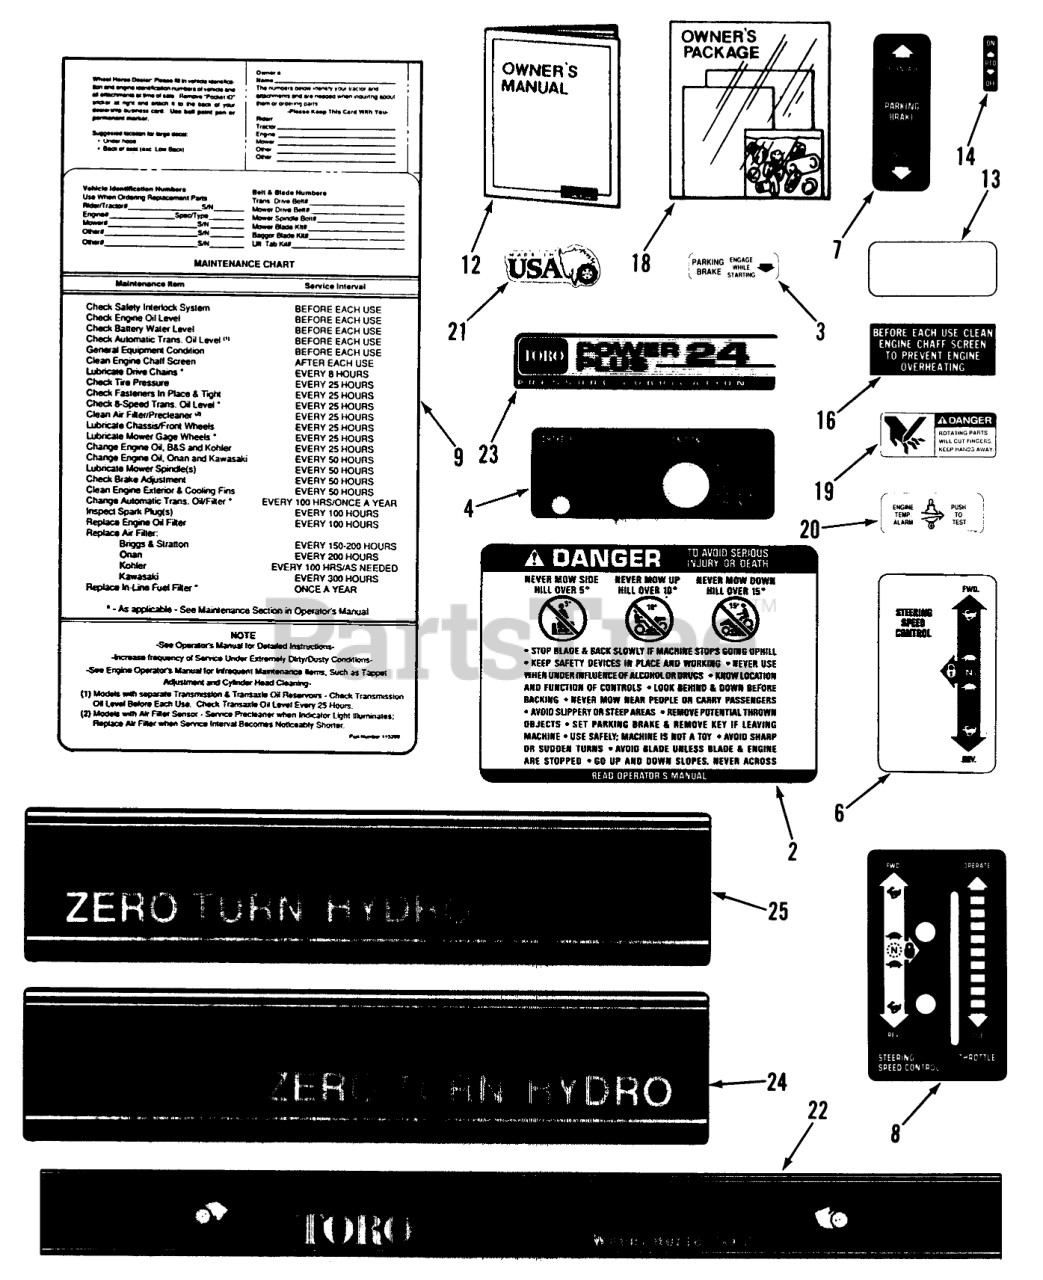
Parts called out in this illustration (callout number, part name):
2	DECAL-DANGER
3	DECAL-PARKING BRAKE
4	DECAL-CHOKE/IGNITION
6	Decal-SpeedControl
7	Decal-Parking Brake
8	DECAL-STRG THROTTLE
9	MAINTENANCE-DECAL
12	700-Series Owner-s Manual
13	DECAL-OVERLAY
14	DECAL-PTO
16	DECAL-ENGINE SCREEN
18	New Tractor Loose Parts Package
19	DECAL-DANGER
20	Decal-Temperature Alarm
21	DECAL-MADE IN USA BK
22	Decal-Hood
23	DECAL-PWR PLUS 24 PL
24	DECAL-ZERO TURN R.H.
25	DECAL-ZERO TURN L.H.
